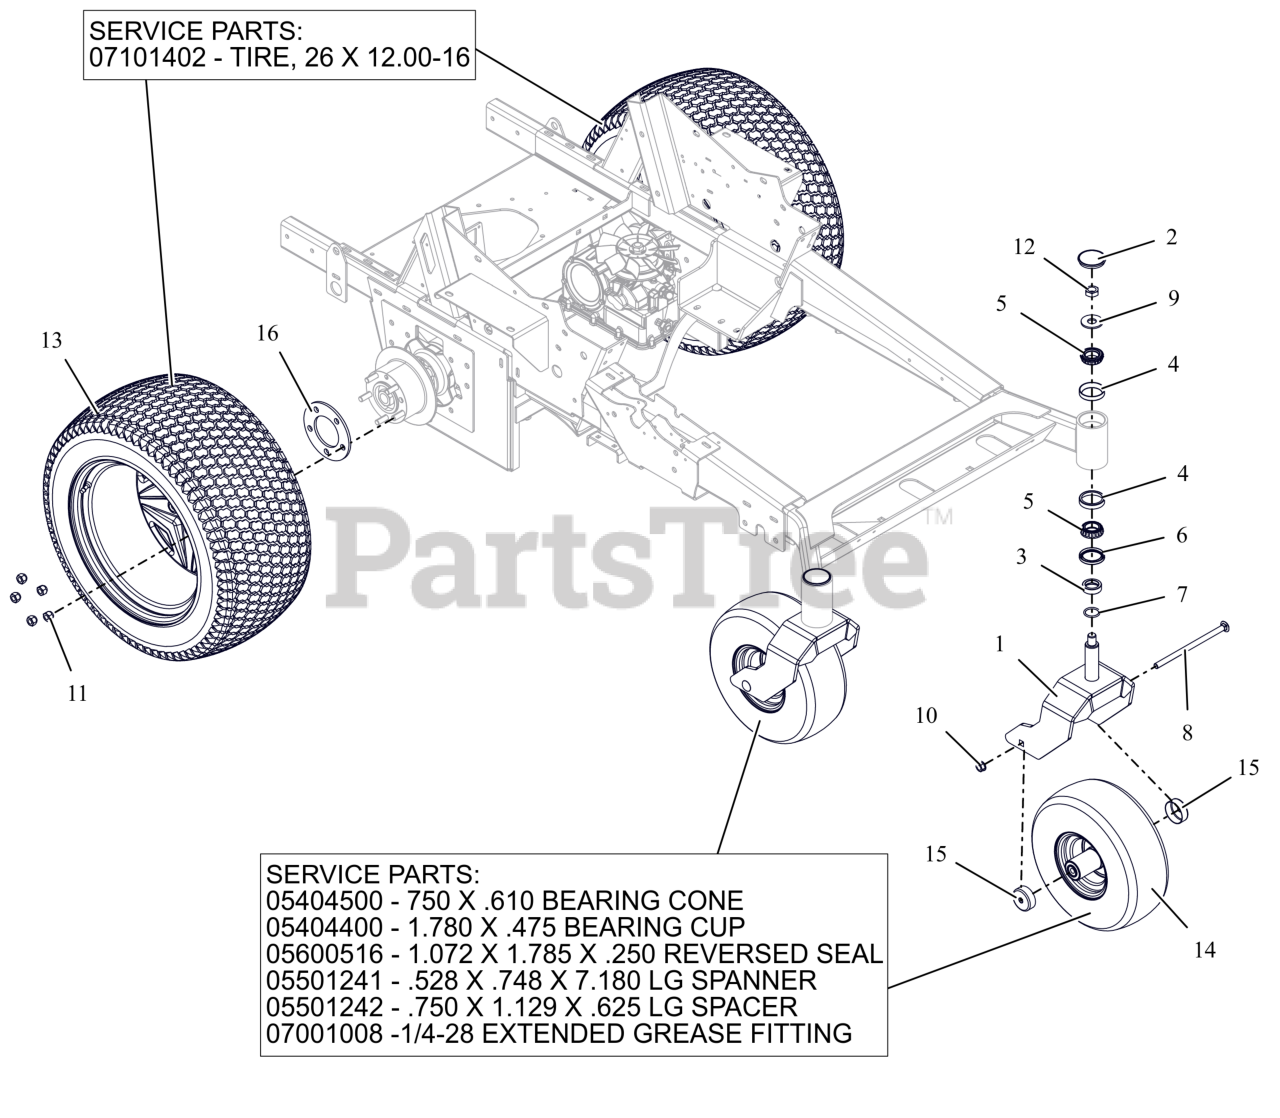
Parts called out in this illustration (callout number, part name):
1	WLDMT, CASTER FORK (RED)
2	CAP, DUST
3	SPCR, FRONT CASTER FORK
4	BRG-CUP 2.328X.465
5	BRG-CONE 1.25X.66
6	SEAL, OIL 1.75 X 2.332 X .312
8	BLT-RHSN .50-13X9.00 G5 ZCC NS
9	WSHR-FL-STL 0.812X2X0.148 ZCC
10	NUT-LK-CTR-FLG .500-13 GG ZCC
11	NUT, WHEEL .50-20 ZCC
12	NUT, JAM-TOPLOCK .750-16 ZCC
13	ASM, WHEEL /TIRE 26 X 12.00-16
13	TIRE, 26 X 12.00-16
13	TUBE, 26X12-16 TIRE
14	ASM, TIRE/WHEEL 15 X 6.00-6 SEMI
14	BRG-CONE .750X.61
14	BRG-CUP 1.781X.475
14	SEAL,1.072X1.785X.250 REVERSED
14	SPANNER, .528X.748X7.18 LG
14	SPACER, .750X1.129X.625 LG
14	GREASE FITTING 1/4-28 EXTENDED
14	TUBE 15X6-6
15	SHIELD, WHEEL BEARING
16	SPCR, PT600 WHEEL (BLACK)
